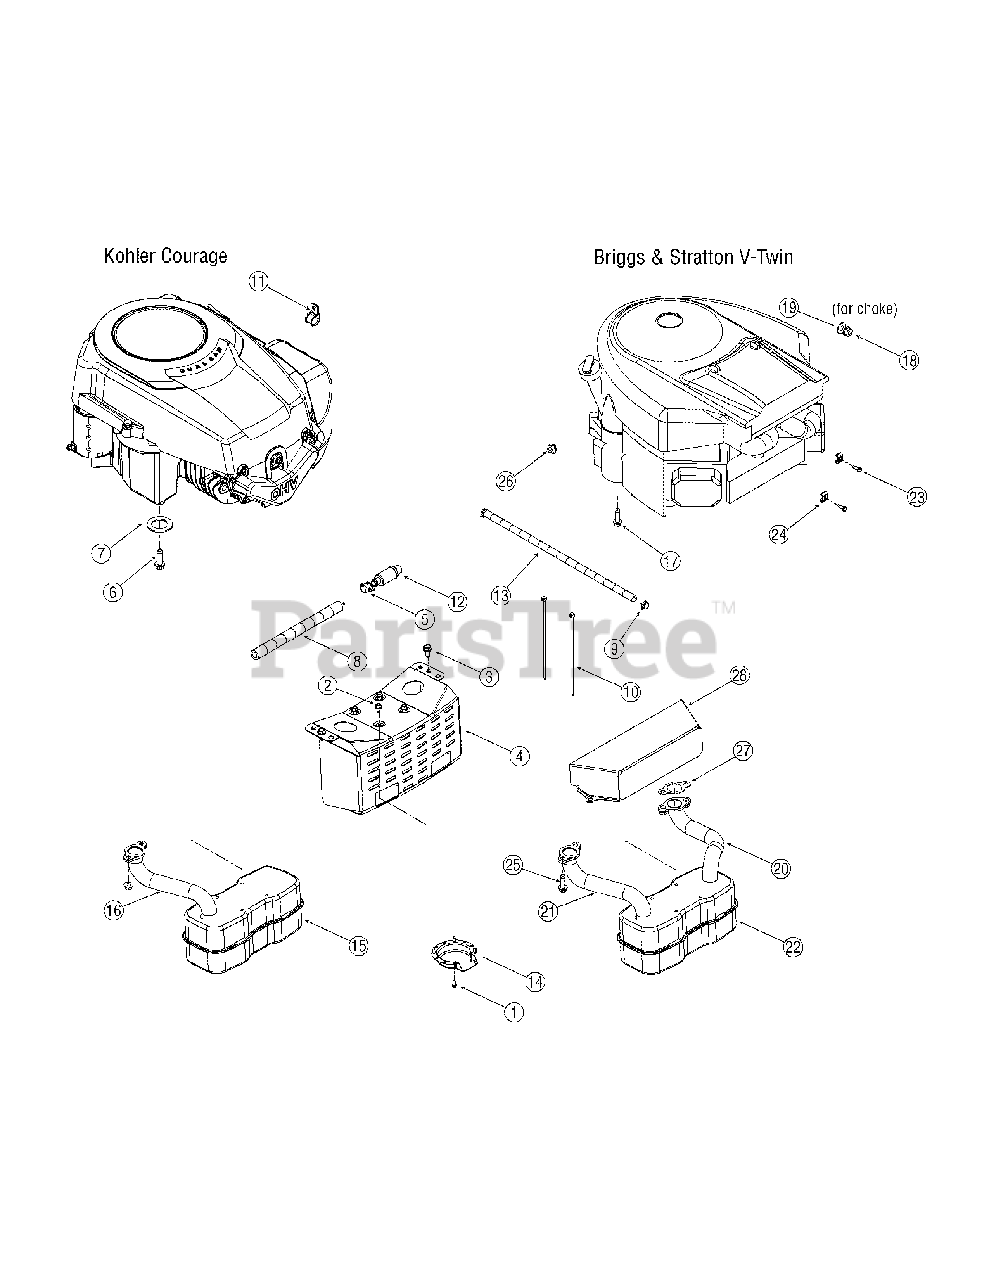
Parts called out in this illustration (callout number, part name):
1	AB Screw #8-18 x 0.5
2	TT Screw 1/4-20 x 0.5
3	AB Screw 5/16-12 x 0.5
4	Muffler Bracket
5	Oil Drain Cap
6	TT Screw 3/8-16 x 1.00 (Kohler Courage)
7	Flat Washer, 1.031 x 1.620 x.095 (Kohler Courage)
8	OIl Drain Extension Hose
9	Hose Clamp
10	Cable Tie
11	Clamp (Kohler Courage)
12	Oil Drain Valve
13	Fuel Line Hose
14	Muffler Deflector
15	Single Inlet Muffler (Kohler Courage)
16	Exhaust Pipe (Kohler Courage)
17	Screw, 3/8-16 x 1.250 (Briggs & Stratton V-Twin)
18	Flange Lock Nut, 3/8-16 (Briggs & Stratton V-Twin)
19	Flat Washer, .406 x .875 x .059 (Briggs & Stratton V-Twin)
20	LH Exhaust Pipe (Briggs & Stratton V-Twin)
21	RH Exhaust Pipe (Briggs & Stratton V-Twin)
22	Dual Inlet Muffler (Briggs & Stratton V-Twin)
23	Screw, #10-32 x .625 (Briggs & Stratton V-Twin)
24	Clamp (Briggs & Stratton V-Twin)
25	Screw, 5/16-18 x .750
26	Sems Nut, 1/4-20 (Briggs & Stratton V-Twin)
27	Exhaust Gasket (Briggs & Stratton V-Twin)
28	Heat Shield (Briggs & Stratton V-Twin)
